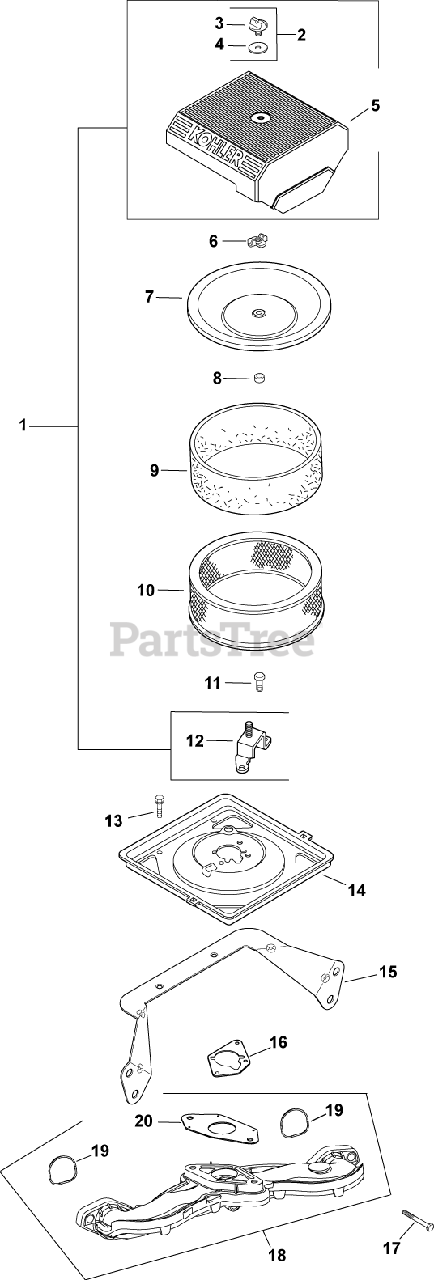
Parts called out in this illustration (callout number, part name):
1	KIT, AIR CLEANER COVER
2	KIT, KNOB W/SEAL
3	KNOB, COVER
5	COVER, AIR CLEANER
6	NUT, WING
7	COVER, INNER AIR CLEANER
8	SEAL, INNER AIR CLEANER
9	ELEMENT, PRECLEANER (LOW)
10	ELEMENT, AIR CLEANER - Also available Retail Packaged 47 883 03-S1 Air Filter Kit
11	SCREW,FLG THD FRM M6X1.0X20-(#25086396S)
12	BRACKET,AIR CLEANERBASE-USE 24 126 206-S
13	SCREW, FLG THD FRM M5X.8X10
14	BASE, AIR CLEANER-USE 24 094 84-S
15	BRACKET, AIR CLEANER BASE
16	GASKET, AIR CLEANER BASE
17	SCREW, FLG M6X1.0X40
18	KIT, INTAKE MANIFOLD
19	O-RING, INTAKE PORT
20	GASKET, CARBURETOR
